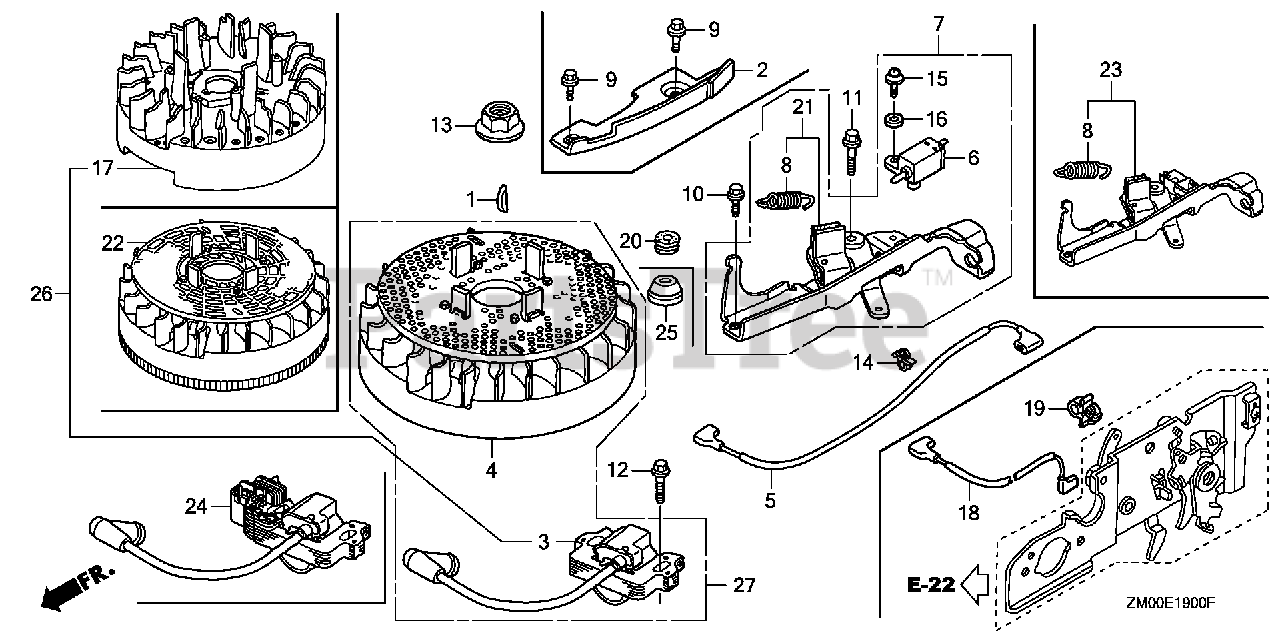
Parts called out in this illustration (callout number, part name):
1	KEY, SPECIAL WOODRUFF (25X18)
3	COIL ASSY., IGNITION (USE FOR F/W OF TEC) (TEC)
8	SPRING, BRAKE LEVER
10	BOLT, FLANGE (6X14) (CT200)
11	BOLT, FLANGE (6X23) (CT200)
12	BOLT, FLANGE (6X23) (CT200)
13	NUT, SPECIAL (14MM)
22	FLYWHEEL ASSY.
23	BRAKE SUB-ASSY.
